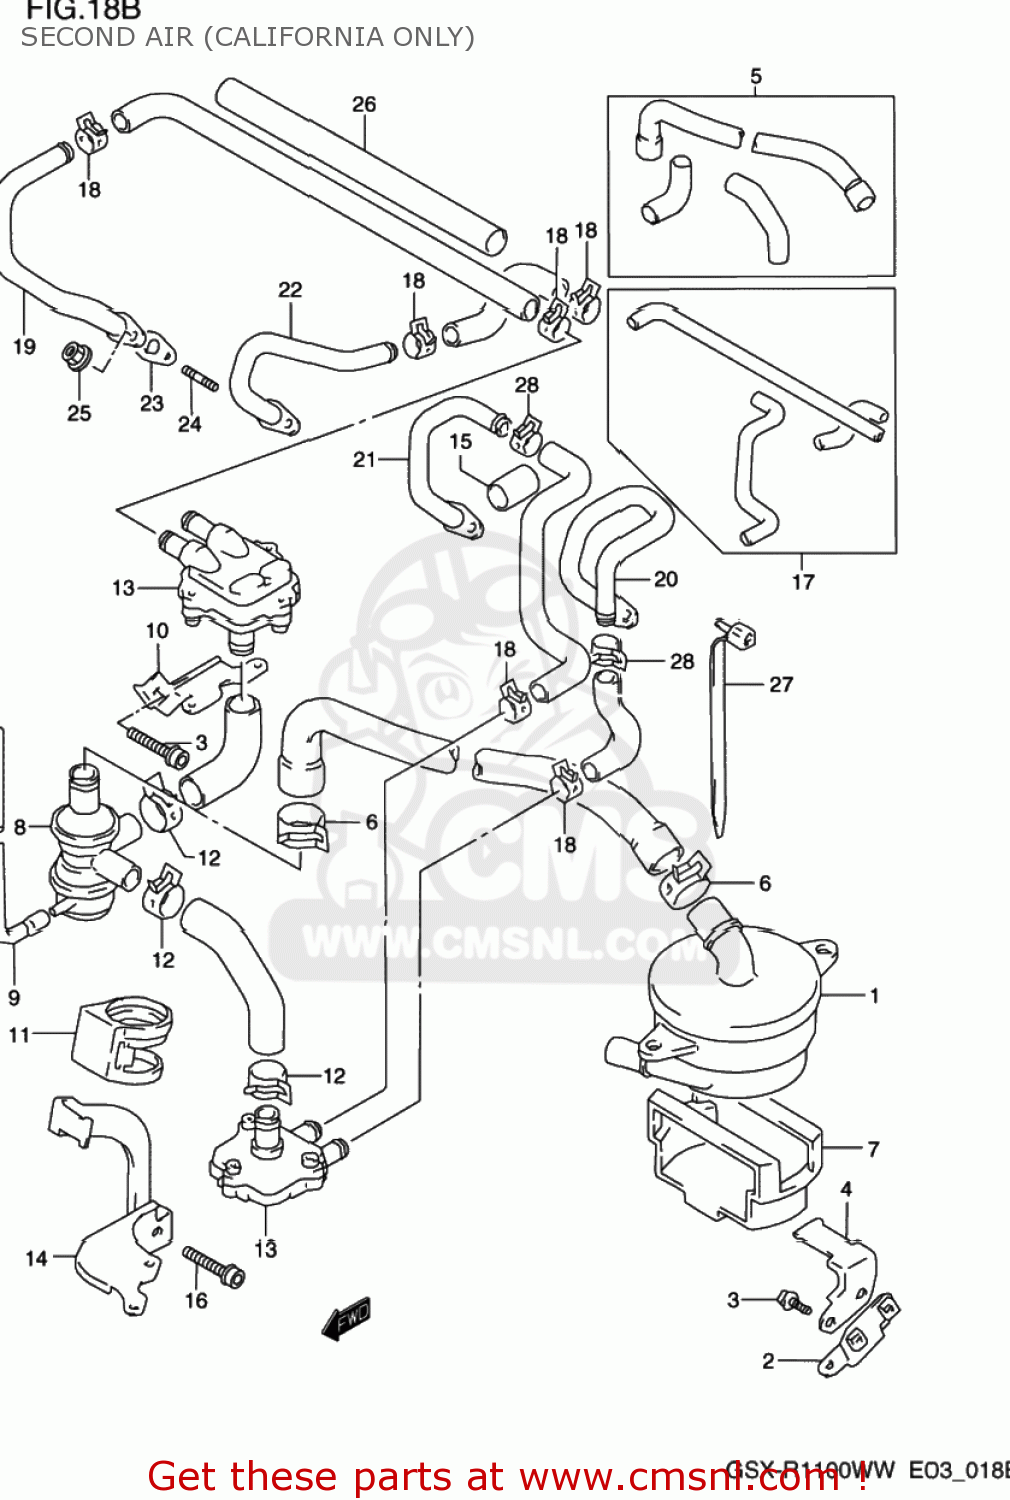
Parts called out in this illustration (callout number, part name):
1	CLEANER ASSEMBLY,SECOND AIR
2	BRACKET,SECOND AIR CLEANER
3	BOLT
4	BRACKET,SECOND AIR CLEANER
5	HOSE SET,SECOND AIR NO.2
6	CLIP
7	CUSHION,SECOND AIR CLEANER
8	VALVE ASSEMBLY,SECOND AIR SWITCH
9	HOSE(4.5X8.5X600)
10	BRACKET,SECOND AIR REED VALVE
11	CUSHION,2ND AIR VALVE
12	CLIP
13	VALVE ASSY,2ND AIR REED
14	BRACKET,SECOND AIR VALVE
15	PROTECTOR,REED VALVE
16	BOLT
17	HOSE SET,SECOND AIR NO.1
18	CLIP
19	PIPE,2ND AIR NO.4
20	PIPE,2ND AIR NO.1
21	PIPE,2ND AIR NO.2
22	PIPE COMP,SECOND AIR NO.3
23	GASKET,SECOND AIR PIPE (N (NAS)
24	STUD 6X16
25	NUT
26	PROTECTOR,REED VALVE H
27	CLAMP(L:165)
